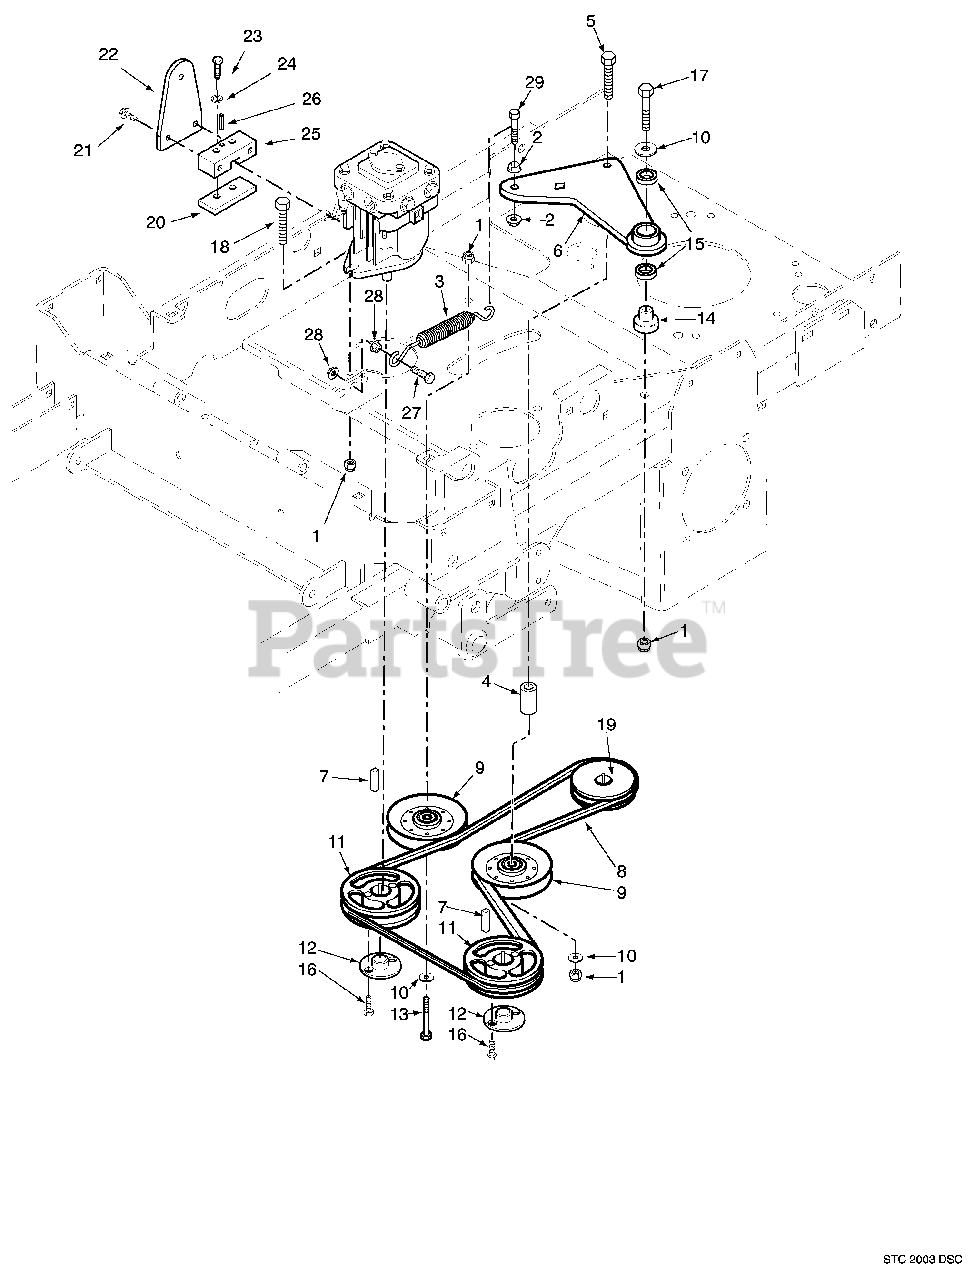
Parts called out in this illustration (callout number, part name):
1	Nut, Elastic Stop 3/8-16
2	Nut, Serrated Flange 3/8-16
3	Spring, Pump Idler
4	Spacer
5	Bolt, Hex Head 3/8-16 x 2-3/4"
6	Idler Arm Assy., Pump Drive
7	Key, 5 x 5 x 25mm
8	Belt, Transmission
9	Pulley, 3" Dia. Idler
10	Flatwasher, 3/8-.391 x .938 x .105
11	Pulley, 5.45 OD Taper Bore
12	Hub, Tapered, 15mm Bore
13	Bolt, 3/8-16 x 2"
14	Pivot, Idler
15	Bearing
16	Bolt, Hex Head 1/4-20 x 1" Grade 8
17	Bolt, Hex Head 3/8-16 x 2-1/2"
18	Bolt, Hex Head 3/8-16 x 1-1/2"
19	Pulley, 4.45 Dia. - 1" Bore
20	Clamp Plate
21	Hex Head Capscrew, 1/4-20 x 3/4"
22	Control Lever, Pump
23	Hex Head Capscrew, 1/4-20 x 3/4"
24	Lockwasher, 1/4"
25	Block, Pump Control
26	Roll Pin
27	Bolt, Hex Head 3/8-16 x 1-1/2" Grade 8
28	Nut, Serr. Flange 3/8-16
29	Bolt, Hex Head 3/8-16 x 1-1/2" Grade 8
